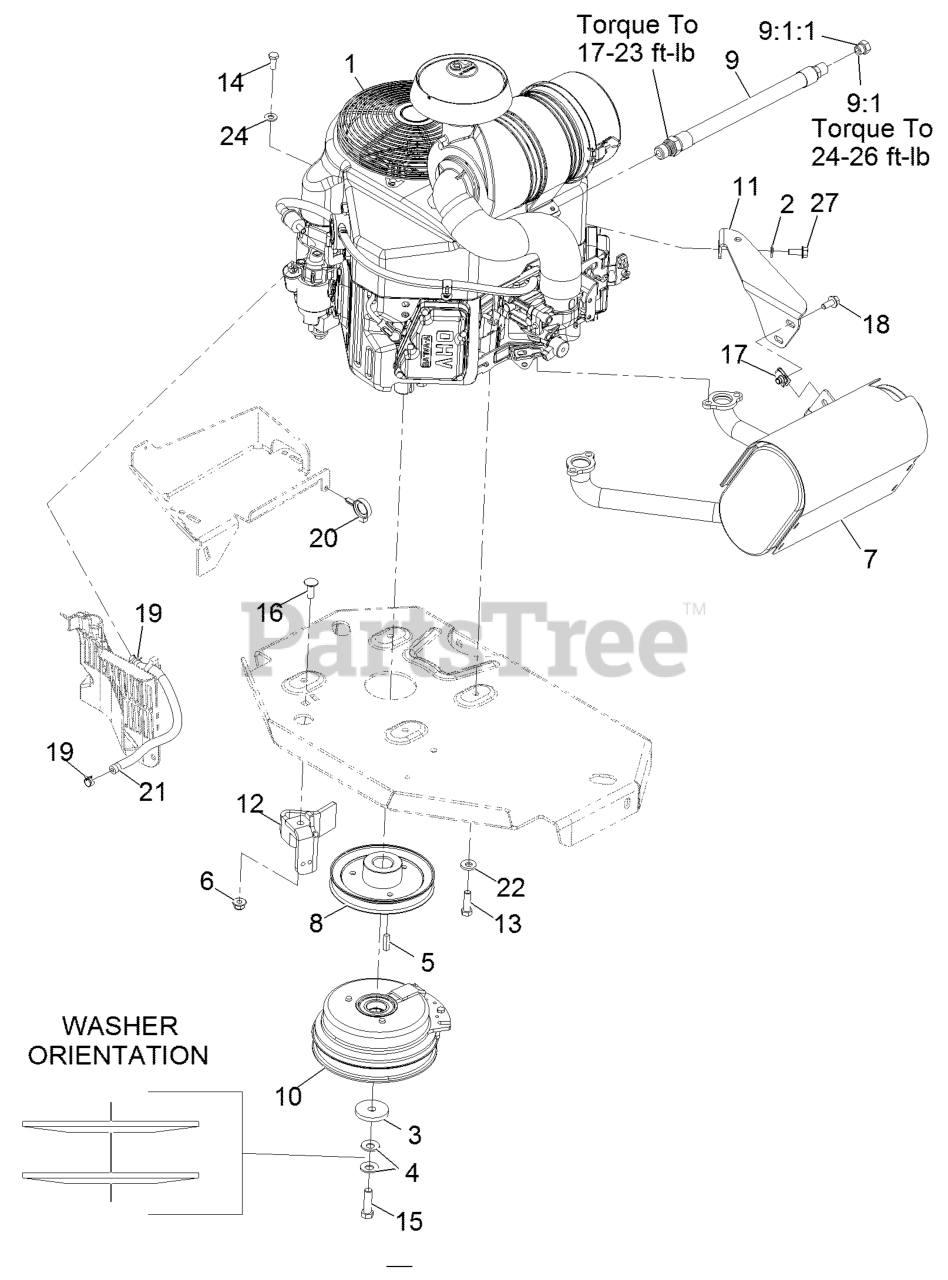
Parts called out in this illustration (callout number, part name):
2	WASHER-SPRING
3	WASHER-CLUTCH
4	WASHER-SPRING
6	NUT-HF, NI
7	MUFFLER
8	SHEAVE
9	ENGINE OIL DRAIN HOSE ASM
9:1	PLUG-HH
9:1:1	O-RING
10	CLUTCH KIT
11	BRACKET-MUFFLER
12	CLUTCH-ANCHOR
13	SCREW-HH
14	SCREW-HH
15	SCREW-HH 7/16-20 X 1 1/2 W/LOCTITE
16	SCREW-CARR
18	SCREW-HHF
19	CLAMP-HOSE
20	CLAMP-HOSE
21	HOSE-FUEL
22	WASHER-BELLEVILLE
24	WASHER-PLAIN
27	SCREW-HHF
